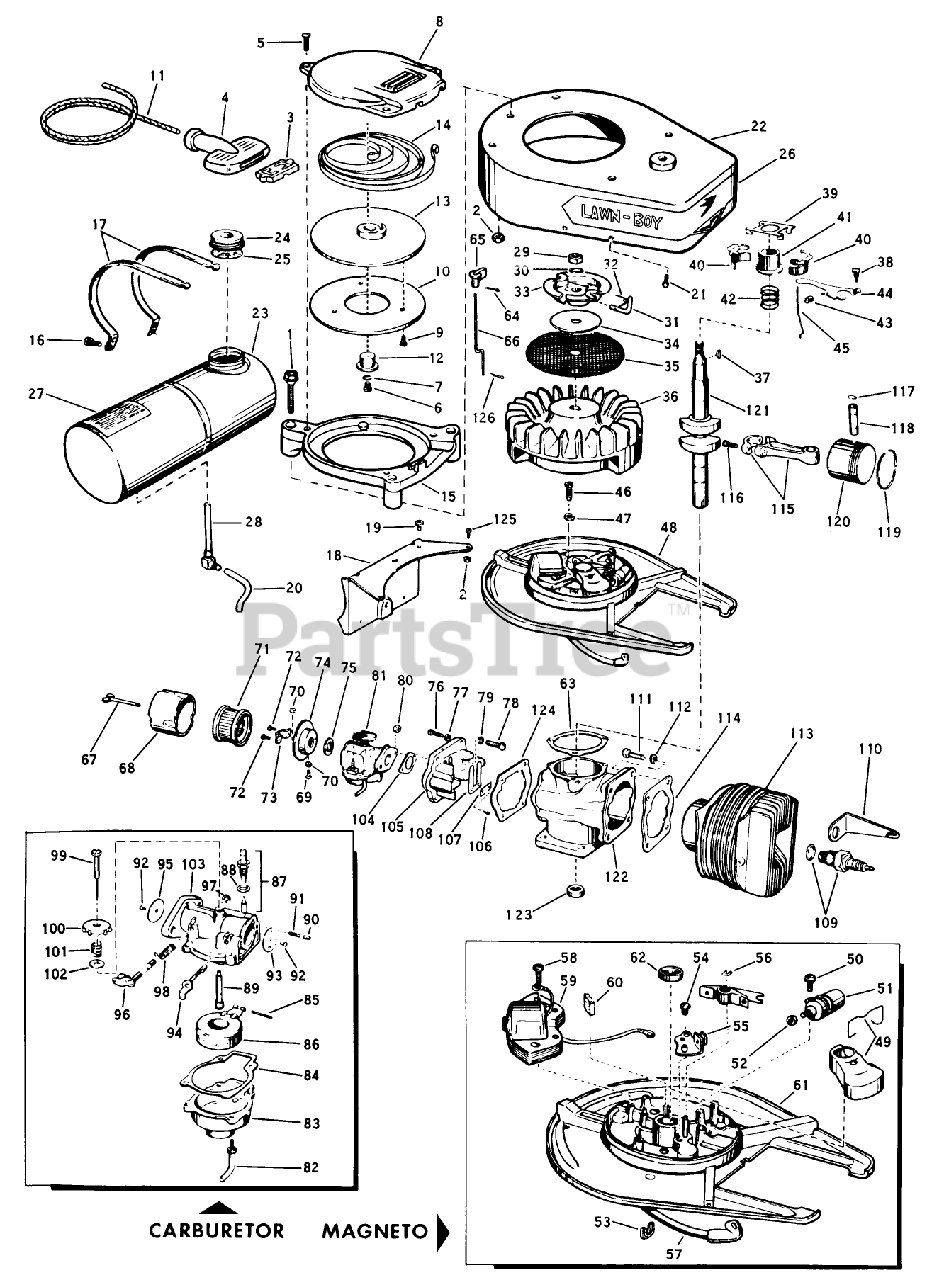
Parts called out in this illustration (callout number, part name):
10	Plate-Pulley
14	RECOIL SPRING
21	SCREW S
24	Gas Cap
31	PIN - STARTER
41	COLLAR S
43	WEAR BLOCK S
44	GOVERNER LEVER AY
45	GOVERNOR ROD S
55	BREAKER AY. S
63	GASKET S
64	Cotter Pin-Choke Knob
65	KNOB, CHOKE BAR
76	SCREW S
80	STOP NUT
92	Screw-Choke Disc
98	SPRING
99	NEEDLE AY. S
101	Spring-Ndl. Adj.
104	GASKET S
107	PLATE-BACKUP, REED
109	Spark Plug
112	Lockwasher-Cylinder to Crankcase Screw
113	Cylinder Sleeve Assembly
116	Screw-Connecting Rod
119	Ring-Piston
121	Crankshaft
124	GASKET
126	Cotter Pin
